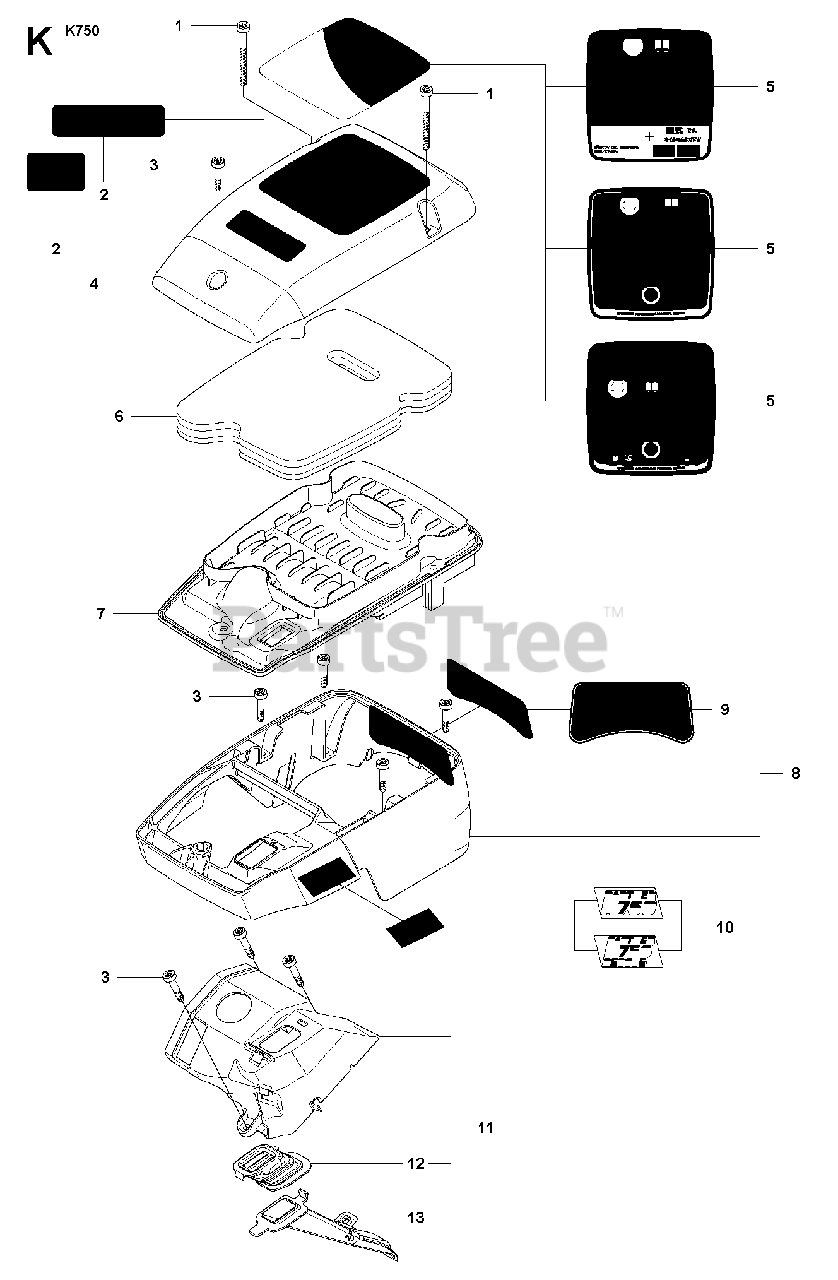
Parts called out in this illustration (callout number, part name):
1	SCREW ITXSCM
3	SCREW ITXSCM
4	FILTER COVER
5	LABELEPA USA
5	LABELEPA Canada
7	FILTER BOTTOM
8	CYLINDER COVER ASSYIncl. 9
8	CYLINDER COVER ASSYIncl. 9, Japan
11	COVERIncl. 12, 13
12	BELLOWS
